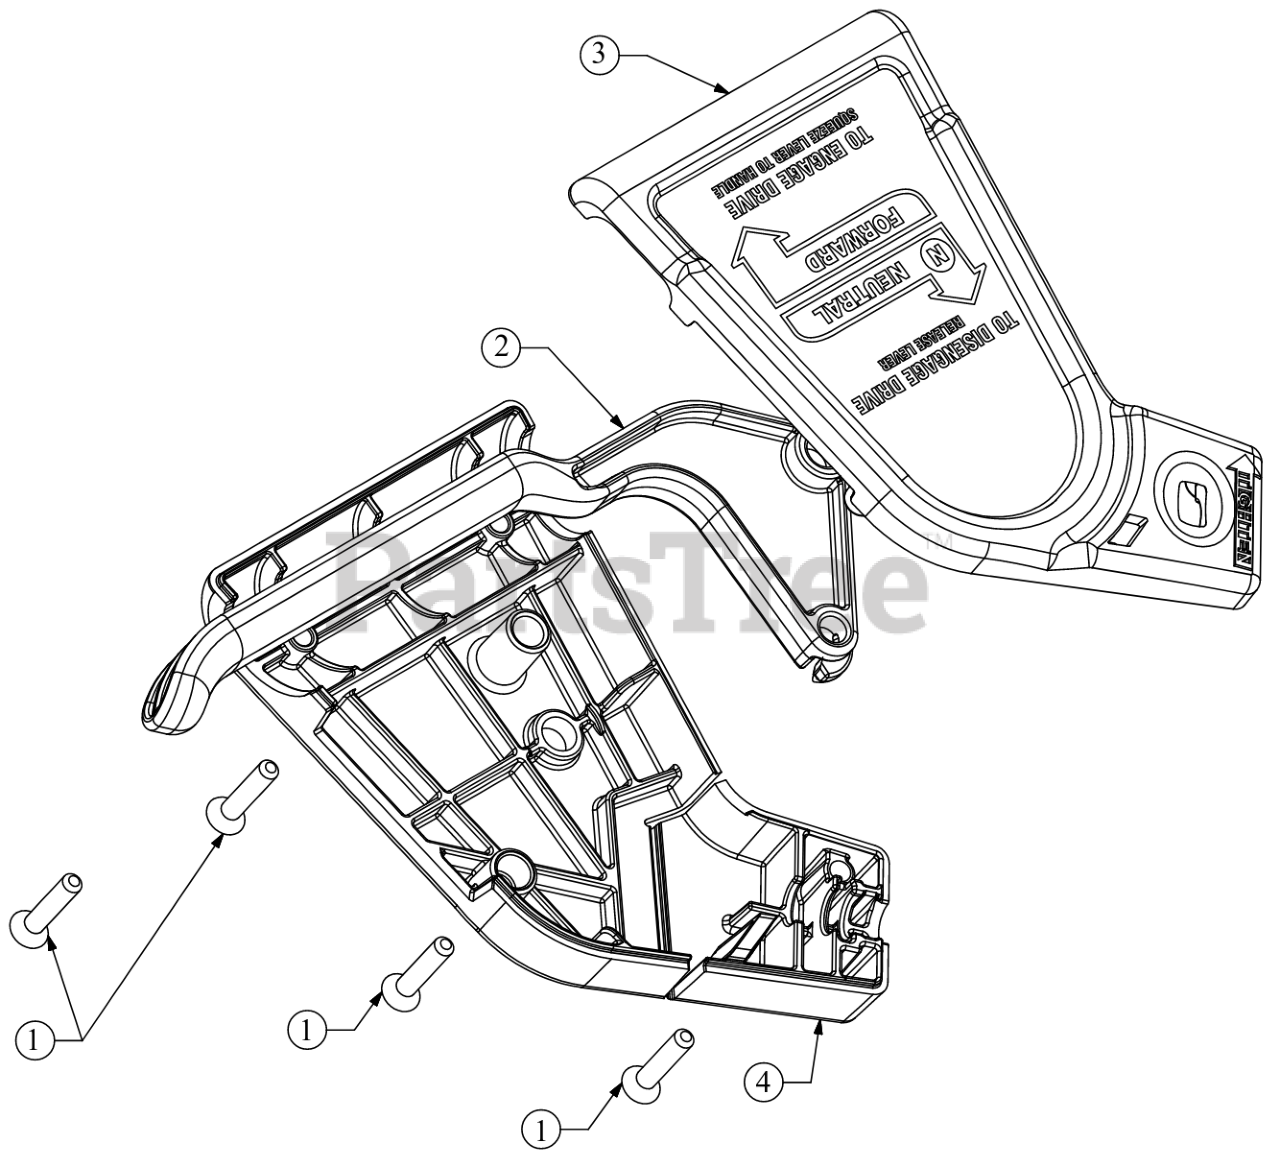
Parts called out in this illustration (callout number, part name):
1	SCREW #10-16 X 1.00
2	ENGAGEMENT LEVER
4	SQUEEZEBOX CONTROL COVER
